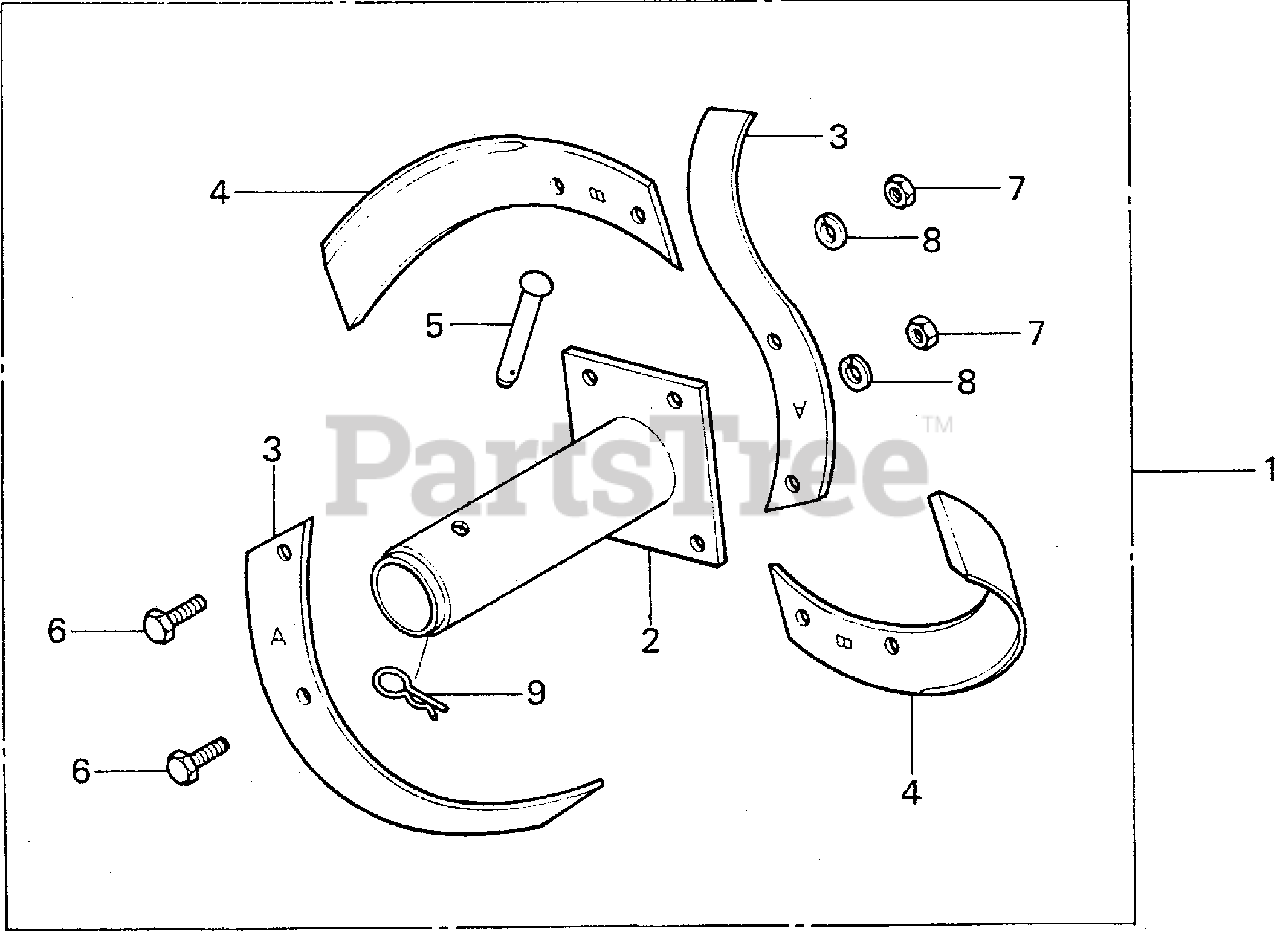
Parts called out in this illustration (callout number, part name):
2	PIPE, EXTENSION
3	TINE A, ROTOR
3	TINE A, ROTARY
4	TINE B, ROTOR
4	TINE B, ROTARY
5	PIN (10X53.5)
6	BOLT, HEX. (10X25)
7	NUT, HEX. (10MM)
8	WASHER, SPRING (10MM)
9	PIN, LOCK (10MM)
